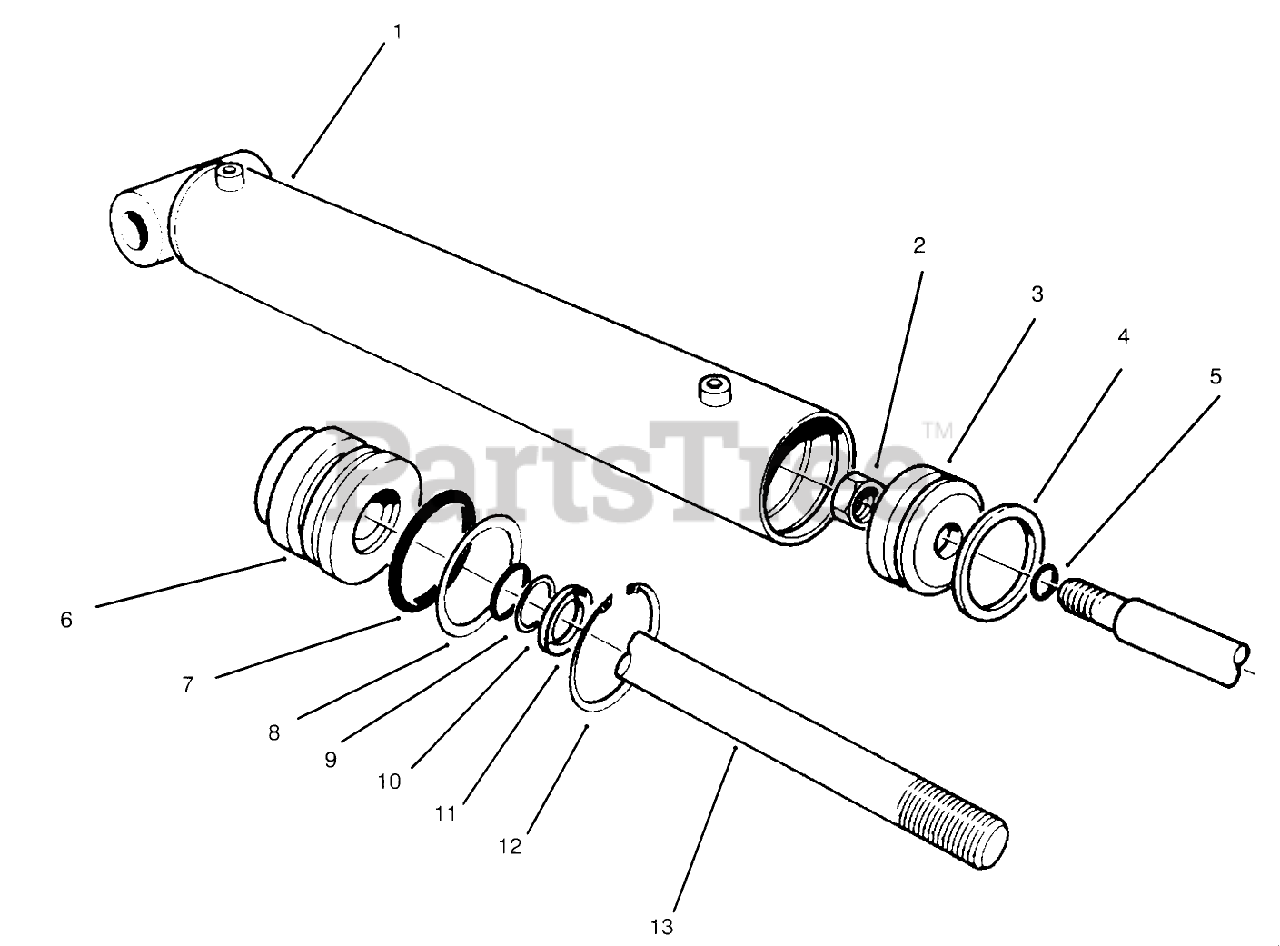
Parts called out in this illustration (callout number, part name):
1	Barrel
2	LOCKNUT
3	PISTON
5	"O"Ring
7	"O"Ring
9	"O"Ring
12	RING-RETAINING
13	SHAFT
